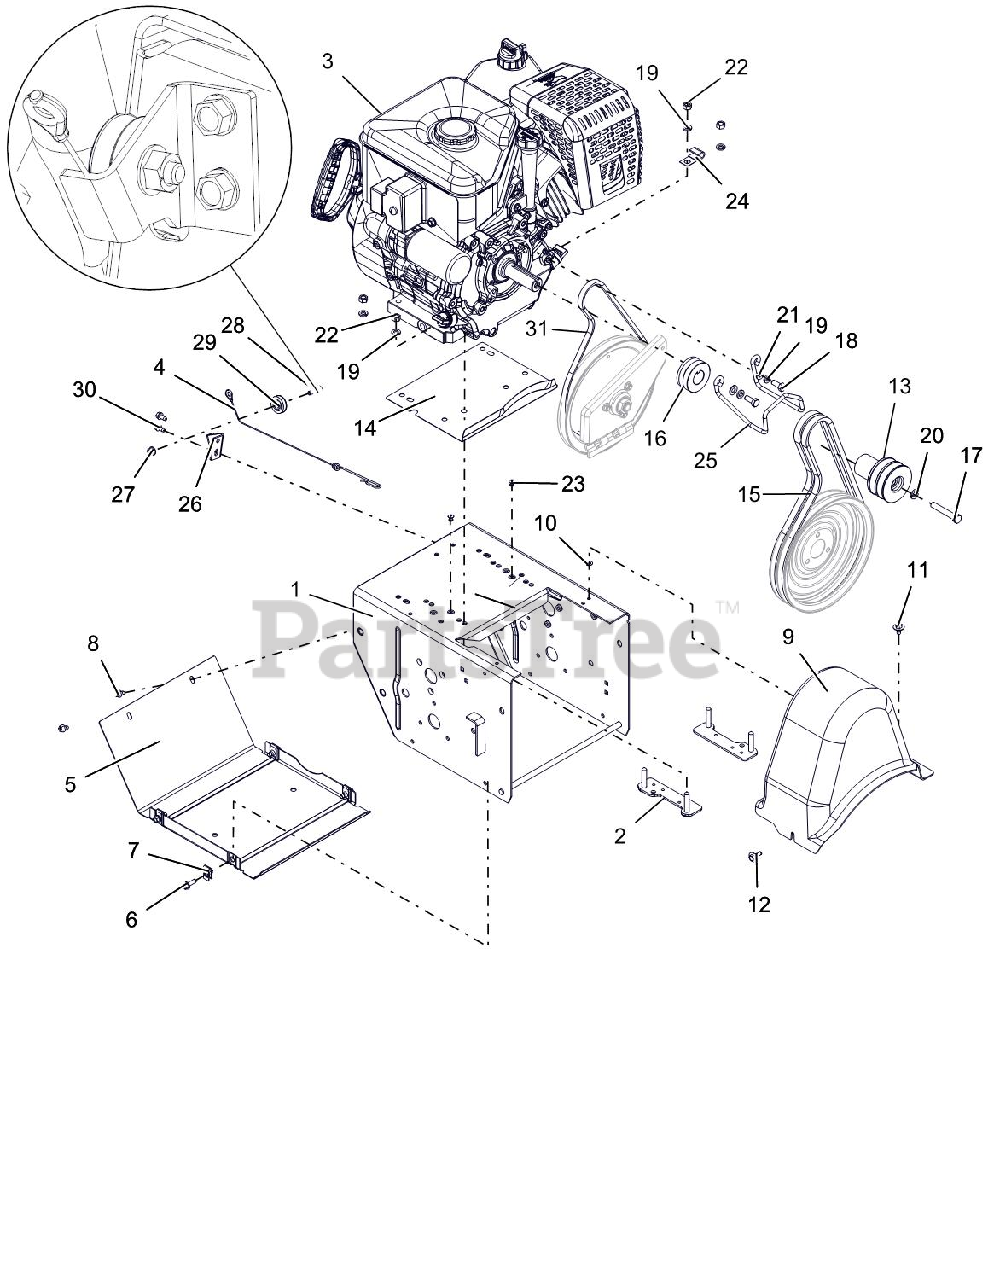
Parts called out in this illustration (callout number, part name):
1	FRAME, MAIN-DELUXE(WELDMENT)
2	STRAP, BOLT-LARGE
3	ENGINE, AX369 GEN 3 240V/60W
4	CABLE, LOWER TRACTION,SS & PRO
5	COVER, BOTTOM
6	BLT-HEX .25-20X.75 HWH YZ GR5
7	NUT-RTNR .25-20X.56
8	SCR-TAP .25-20X.50 HWH TR YWZ
9	COVER, BELT-LARGE
10	NUT-PUSH .25X.50 O.D.
11	SCR-TAP .25-20X.50 LGHWH TR YZ
12	SCR-TAP .25-20X.5 CAPTIVE
13	SHEAVE, ATTACHMENT 2-GRV
14	BAFFLE, WATER - LARGE BLOCK
15	V-BELT, HA-RAW EDGE (SET)
16	SHEAVE, DRIVE
17	BLT-HEX .38-24X2.25 YWZC GR5
18	BLT-HEX .31-24X.75 YWZC GR5
19	WSHR-LK .312X.097 HVY YWZC
20	@WSHR-LK .38X.094 REG YWZC
21	@WSHR-FL-STL.344X.688X.065YWZC
22	@NUT-HEX .31-18 YWZC
23	RVT-POP .187 YZ
24	J-CLAMP
25	FINGER, BELT
26	BRACKET, CABLE PULLEY
27	@NUT-LK-TOP-FLG .25-20 YWZC
28	BOLT, SHLDR-.375X.375X.25-20
29	PULLEY, CABLE
30	SCR-TAP .25-20X.50 HWH TR YWZ
31	V-BELT, 3L-WRAPPED
